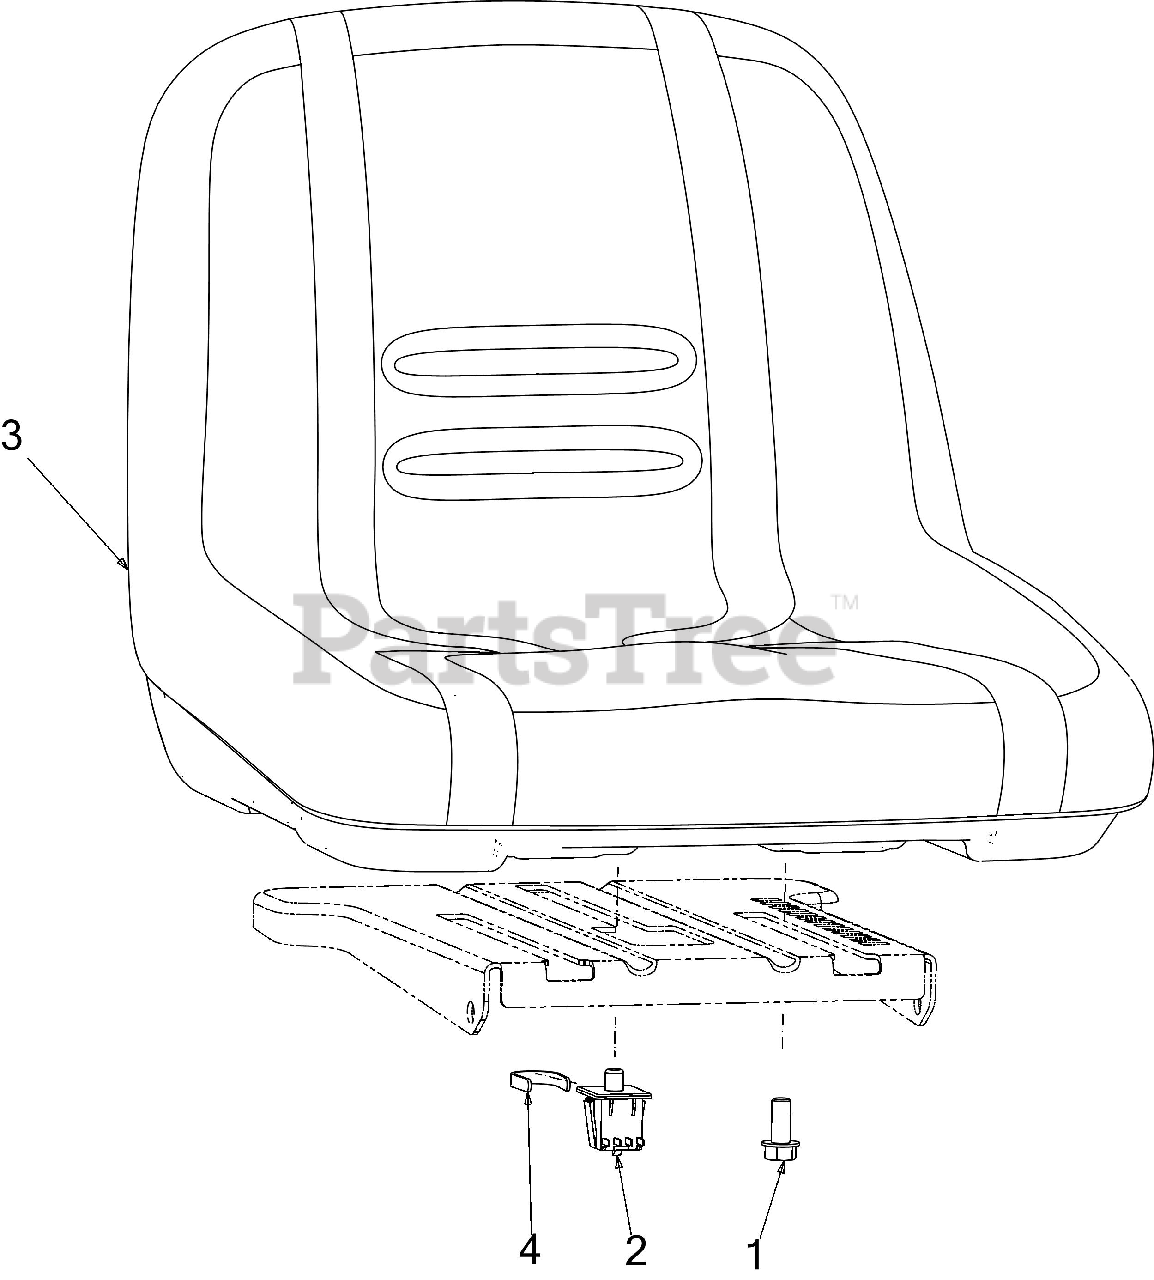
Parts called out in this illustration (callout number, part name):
1	SCREW 3/8-16 x .875 GR5
2	SEAT SWITCH
3	HIGH BACK SEAT
4	RETAINING CLIP
